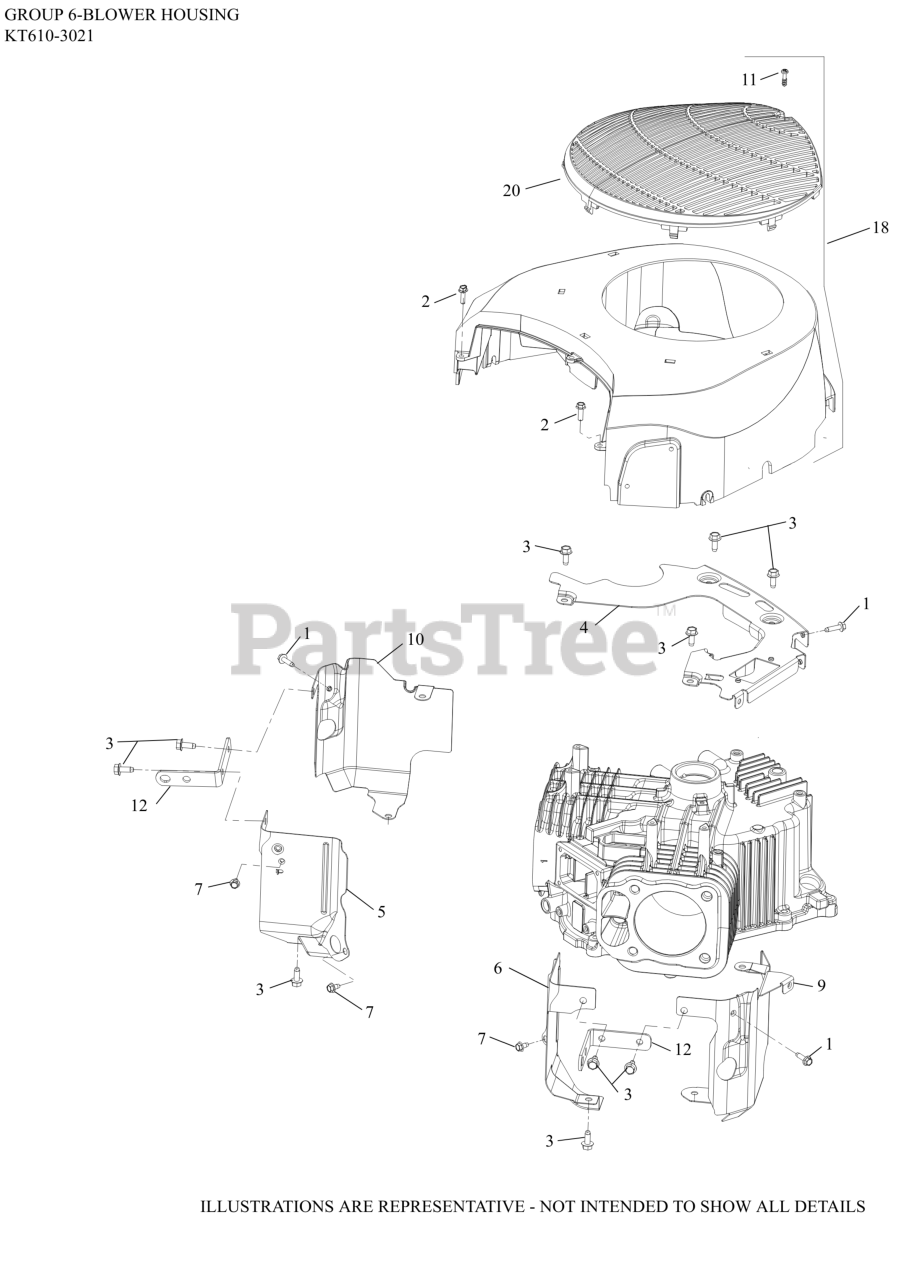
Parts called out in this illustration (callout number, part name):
1	SCREW, THD FRM-USE 25 086 473-S
2	SCREW, HI-LOW
3	SCREW, THREAD FORMING
4	PLATE, BACKING
5	BAFFLE, VALLEY #1
6	BAFFLE, VALLEY #2
7	SCREW, THREAD FORMING
9	BAFFLE, LEFT BARREL
10	BAFFLE, RIGHT BARREL
11	SCREW, M5-2.42 (PT) THREAD
12	STRAP, LIFTING
18	KIT, BLOWER HOUSING
20	GUARD, FIXED
